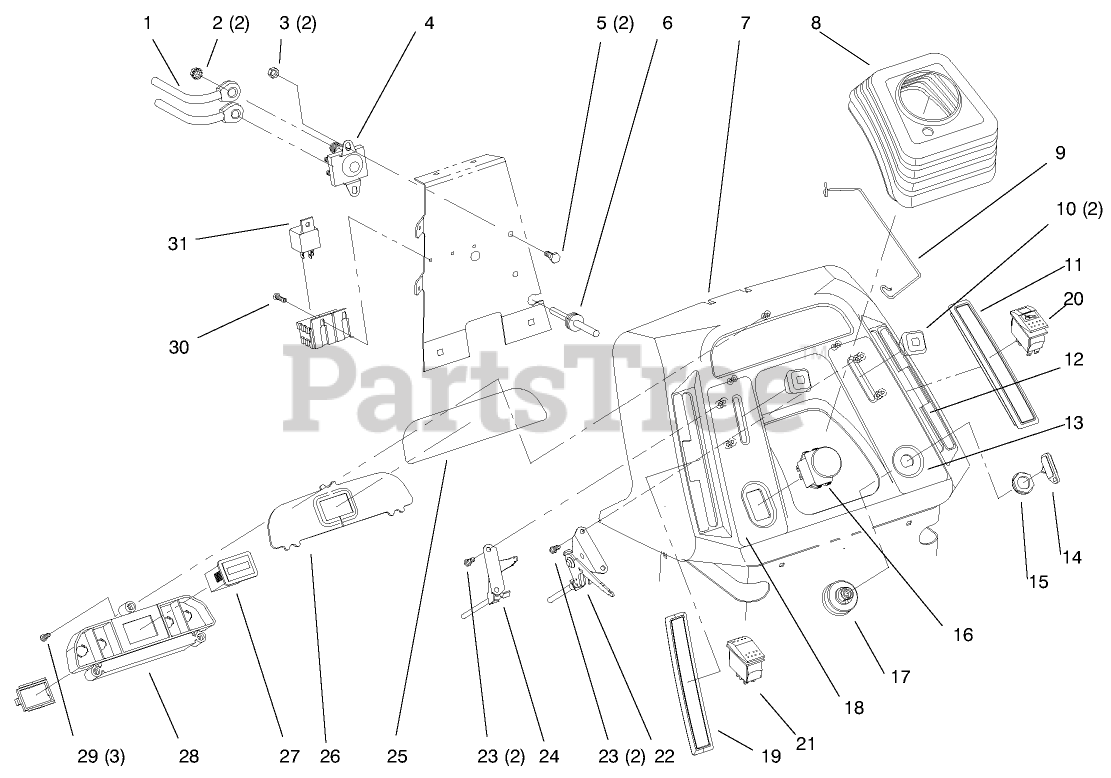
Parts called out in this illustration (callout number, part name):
1	WIRE-21 INCH
2	NUT-KEPS
3	NUT-LOCK, NI
5	SCREW-HH
6	GROMMET-RUBBER
8	BOOT-STEERING
9	CLIP-BOOT
11	COVER-SLOT, RH
13	DECAL-THROTTLE, IGNITION
13	DECAL-DASH
14	KEY-IGNITION
16	SWITCH-PTO,ON-ON-NONE
17	SWITCH-IGNITION
18	DECAL-PTO / CHOKE
18	DECAL-DASH, PTO/CHOKE
19	COVER-SLOT, LH
22	CONTROL-THROTTLE
24	CONTROL-CHOKE
25	DECAL - DASH LENS
26	LENS-DASH
27	HOURMETER
28	HOUSING-LIGHT, INDICATOR
29	SCREW
30	SCREW-PPHTF
31	RELAY
